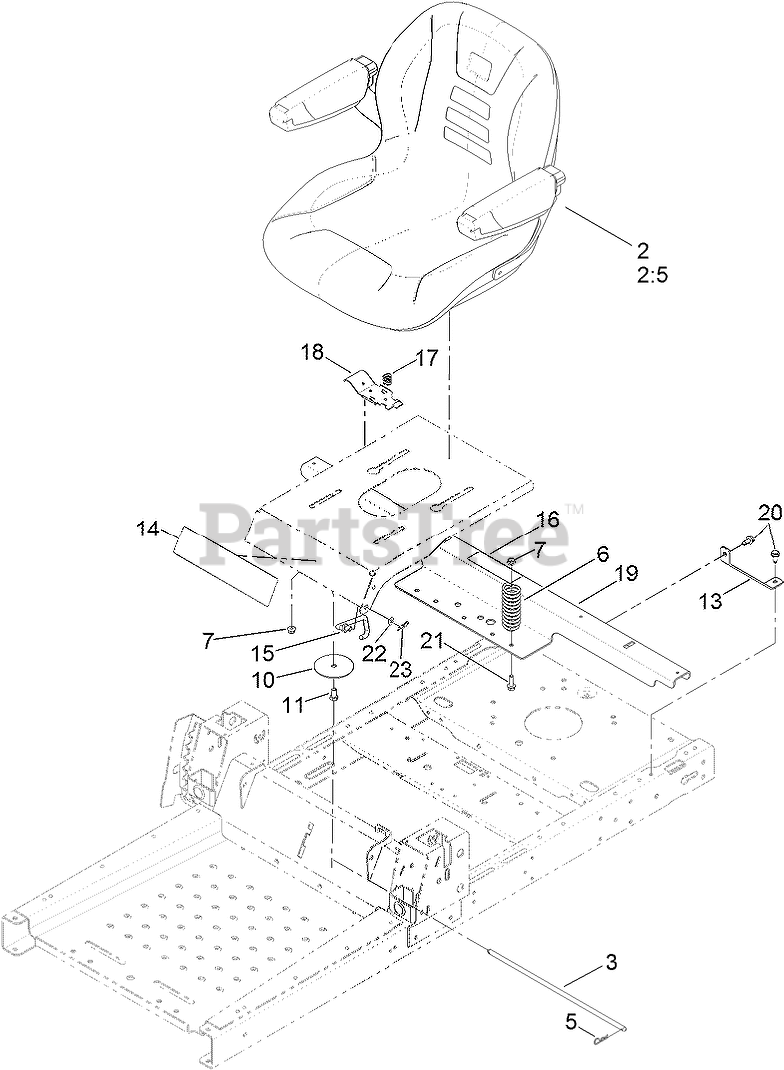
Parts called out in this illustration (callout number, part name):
2	18 INCH SEAT ASM
2:5	ARMREST KIT
3	ROD-STOP
5	PIN-COTTER
6	SPRING-COMPRESSION
7	NUT-HF, NI
10	WASHER-SEAT
11	SCREW-HH
13	SUPPORT-TANK, REAR
14	DECAL-TIMECUTTER
15	STOP-SEAT
16	DECAL-SERVICE, CE
17	SPRING-COMPRESSION
18	LATCH-SEAT
19	SUPPORT-POD
20	SCREW-HWHTF
21	SCREW-HHF
22	WASHER-PLAIN
23	PIN-COTTER
